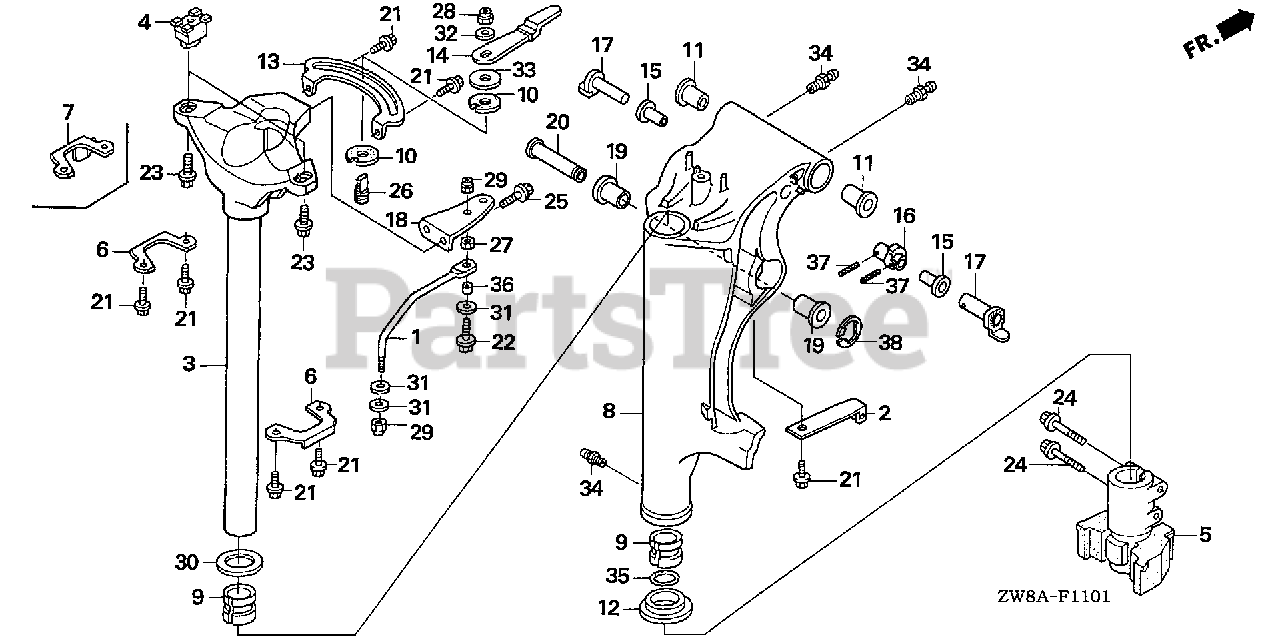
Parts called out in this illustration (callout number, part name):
2	SPRING, CLICK
3	FRAME, MOUNTING (L)
4	RUBBER, MOUNTING (UPPER)
5	RUBBER, MOUNTING (LOWER)
6	COVER, MOUNTING RUBBER (UPPER)
7	COVER, MOUNTING RUBBER (UPPER) (PT)
8	CASE, SWIVEL *NH282MU* (L)(PT) (OYSTER SILVER METALLIC-U)
9	LINER, SWIVEL CASE
10	BLOCK, FRICTION
11	BUSH, SWIVEL CASE
12	COLLAR, SWIVEL CASE
13	PLATE, FRICTION
14	LEVER, FRICTION
15	BUSH, TILT ARM
16	BRACKET, TILTING
17	STOPPER, TILT
19	BUSH, CYLINDER (LOWER)
20	PIN, CYLINDER (UPPER)
21	BOLT, FLANGE (6X12)
23	BOLT, FLANGE (10X25)
24	BOLT, FLANGE (8X45)
26	BOLT, STUD (8X26)
28	NUT, SELF-LOCK (8MM)
30	WASHER, THRUST
32	WASHER (8MM)
33	WASHER, NYLON (8MM)
34	NIPPLE, GREASE
35	O-RING (34X2.4)
37	PIN, SPRING (2.5X20)
38	E-RING (15MM)
